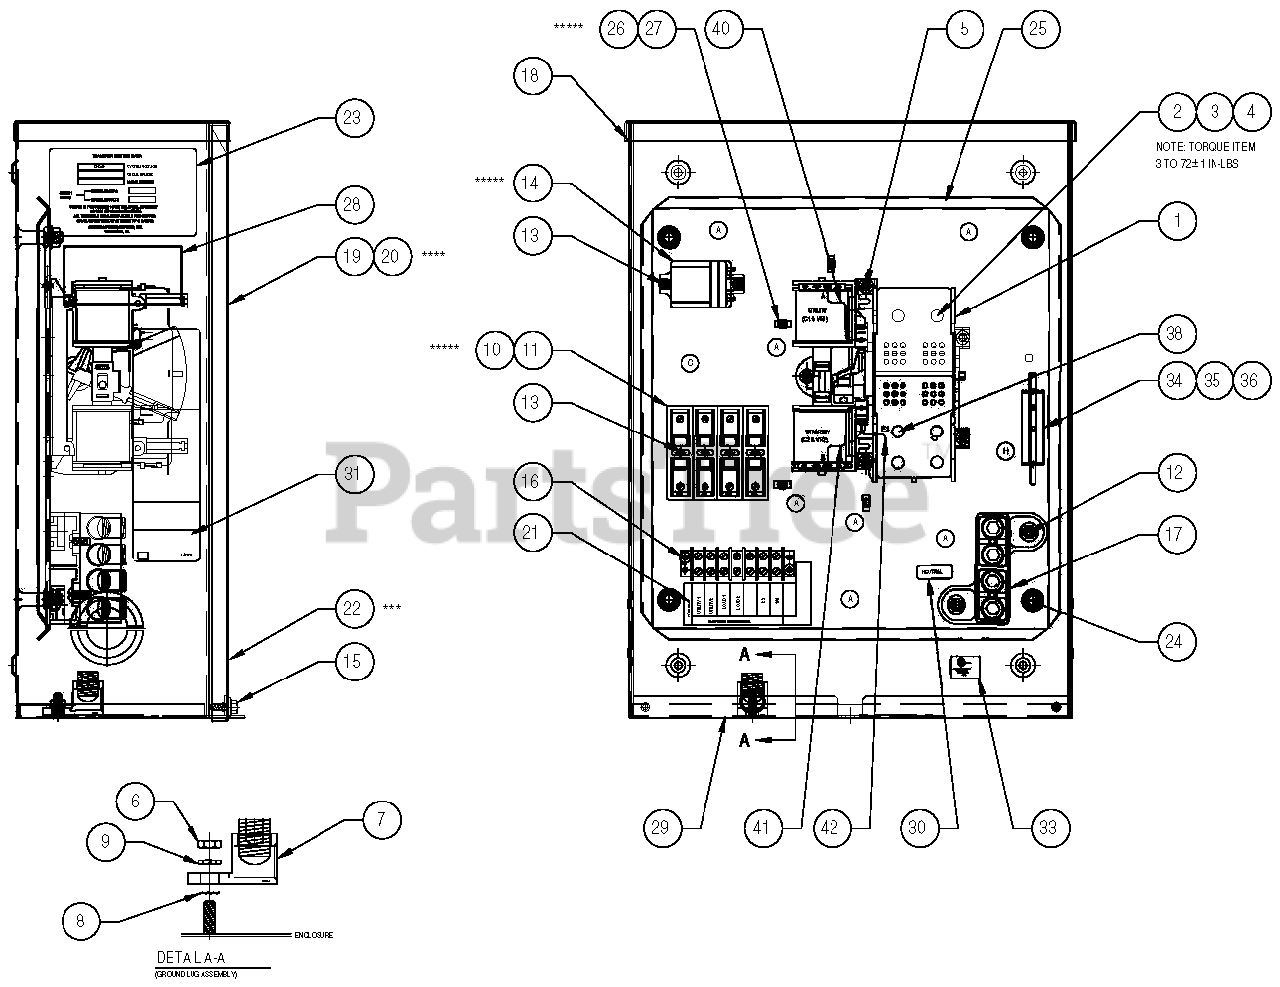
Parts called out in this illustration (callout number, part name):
1	TR SW-HSB 200A 2P 250V
2	LUG SLDLSS 250-#6 AL/CU
3	SCREW BHSC 1/4-20 X 3/8
4	WASHER LOCK M6-1/4
5	SCREW HHTT M5-0.8 X 16 BP
6	NUT HEX M8-1.25 G8 YEL CHR
7	LUG SLDLSS 350-#6 X 13/32 AL/CU
8	WASHER SHAKEPROOF EXT 5/16 STL
9	WASHER LOCK M8-5/16
10	FUSE 5A X BUSS
11	FUSE HOLDER
12	SCREW HHTT M6-1.0 X 12 ZINC
13	SCREW HHTT M4-0.7 X 10 BP
14	RELAY PNL 12VDC DPDT 10A@240VA
15	SCREW TH-FRM M6-1 X 16 N WA Z/JS
16	RIVET POP .156 X .675 AL
17	ASS'Y-NTRL BL150-200A
18	WELDMENT XFER SW BOX HSB
19	COVER TRANSFER SWITCH BOX HSB
21	DECAL TERMINAL STRIP
22	DECAL-LIVE CIRCUIT
23	DECAL SWITCH RATING
24	NUT LOCK FL 3/8-16
25	SUBPLT TRANSFER SWITCH HSB
26	HOLDER CABLE TIE
27	TIE WRAP UL 3.9" X .10" NATL
28	DECAL TRANSFER SWITCH DATA 200
29	DECAL GROUND LUG
30	DECAL NEUTRAL
31	DECAL MANUAL 5A FUSE
32	DECAL TEST SEQUENCE 2P TS 3R
33	DECAL-UL LIST HSB
34	BRACKET ARM EXTENDER
35	SCREW HWHS #6-25 X 3/8 ZNC
36	ARM EXTENDER PIN
37	HARN 100/200A 2P HS
38	90 DEGREE DN SPADE CONNECTOR
42	WIRE-E1
